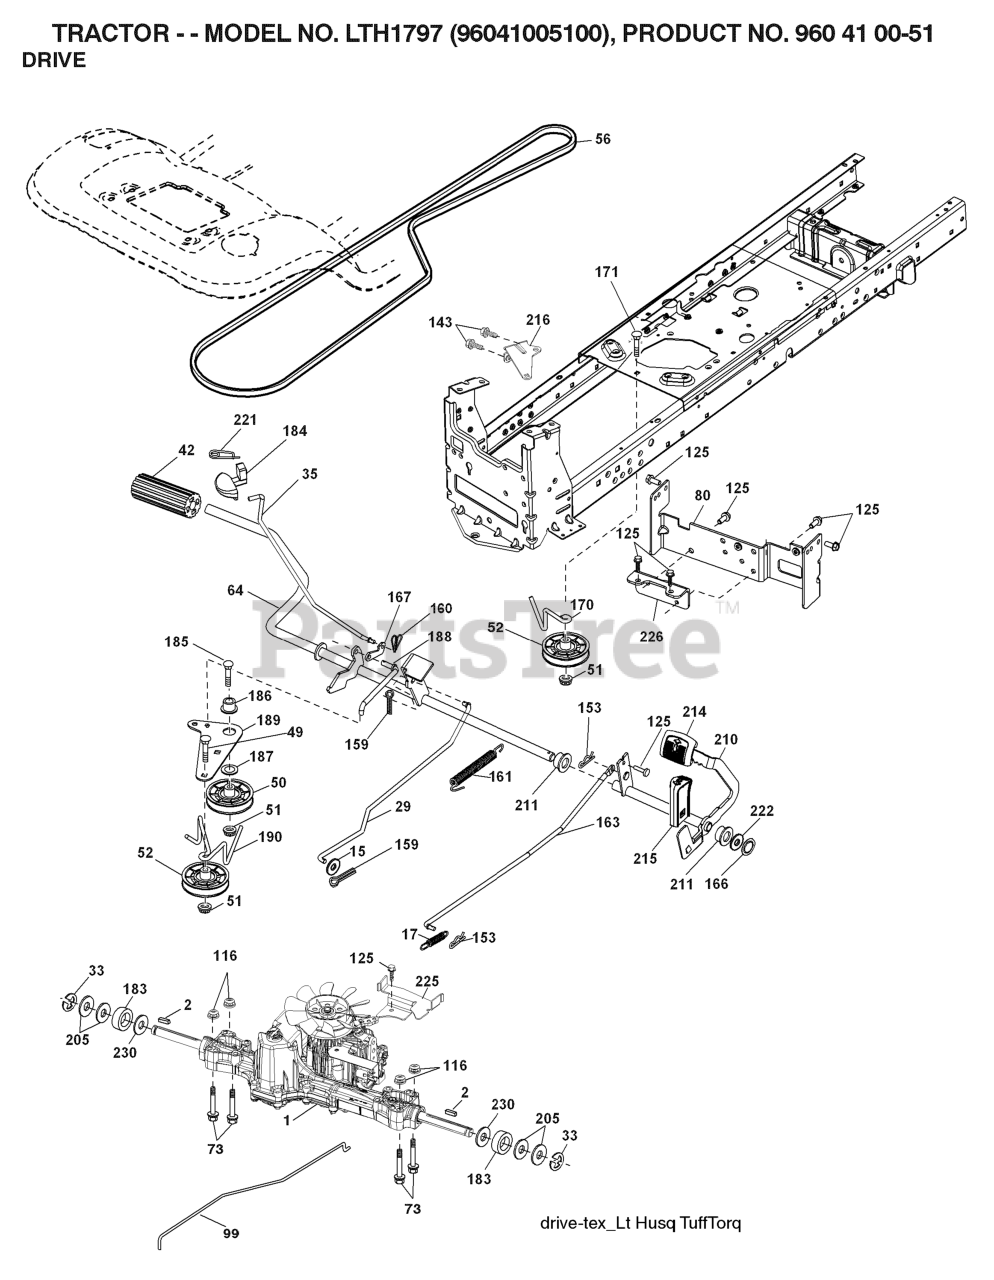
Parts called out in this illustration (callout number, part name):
2	SQUARE KEY
15	WASHER
17	SPRING.BRAKE.K46.GREEN
29	ROD.BRAKE.K46
35	ROD.CNTRL.PARK.PREDATOR.LT.TEX
42	PEDAL COVER T
50	IDLER.FLAT.910.OFFSET
51	NUT LOCK FLG 3/8-16 UNC
52	IDLER.V-GROOVE.910.OFFSET
56	V-BELT.MOWER.92.40.42/K46
64	SHAFT.ASM.PEDAL.BRK.CNTR
73	BOLT HEX 5/16-18 GR 5
80	STRAP TORQUE
99	ROD ASM BYPASS
116	NUT LOCK HEX FLANGE 5/16-18
125	SCREW
143	Screw 5/16-18 x 1/2 Hex, Self Tapping 5/16-18 x 1/2
153	RETAINER M
159	COTTER PIN
160	RETAINER CLIP
163	ROD.CONTROL.PEDAL.K46
166	NUT.PUSH.625.2006
167	LATCH.BRAKE.SPRING
170	KEEPER.V-IDLER.CENTER.
183	SPACER AXLE
184	HANDLE PARKING BRAKE
186	SPACER.RETAINER
187	WASHER 12/32X2X10GA
188	RP.LINK.CLUTCH.GROUND.DRIVE
189	BELLCRANK.GROUND.DRIVE.TEX.
190	KEEPER.BELLCRANK.DRIVE
210	ROCKER.ASM.PEDAL.CONTR
211	BEARING.NYLON
214	PEDAL.FORWARD.TEX.GT.4
215	PEDAL.REVERSE.TEX.GT.4
216	BRACKET.PULLEY.IDLER.W/TEX
221	RETAINER.SPRING.CLIP.H
222	WASHER 21/32 X 1-1/4 X 10 GA.
225	KEEPER.BELT.TRANSAXLE.K46
226	BRACKET.MOUNT.TORQUE.K46.TLT
230	WASHER.HARDENED
